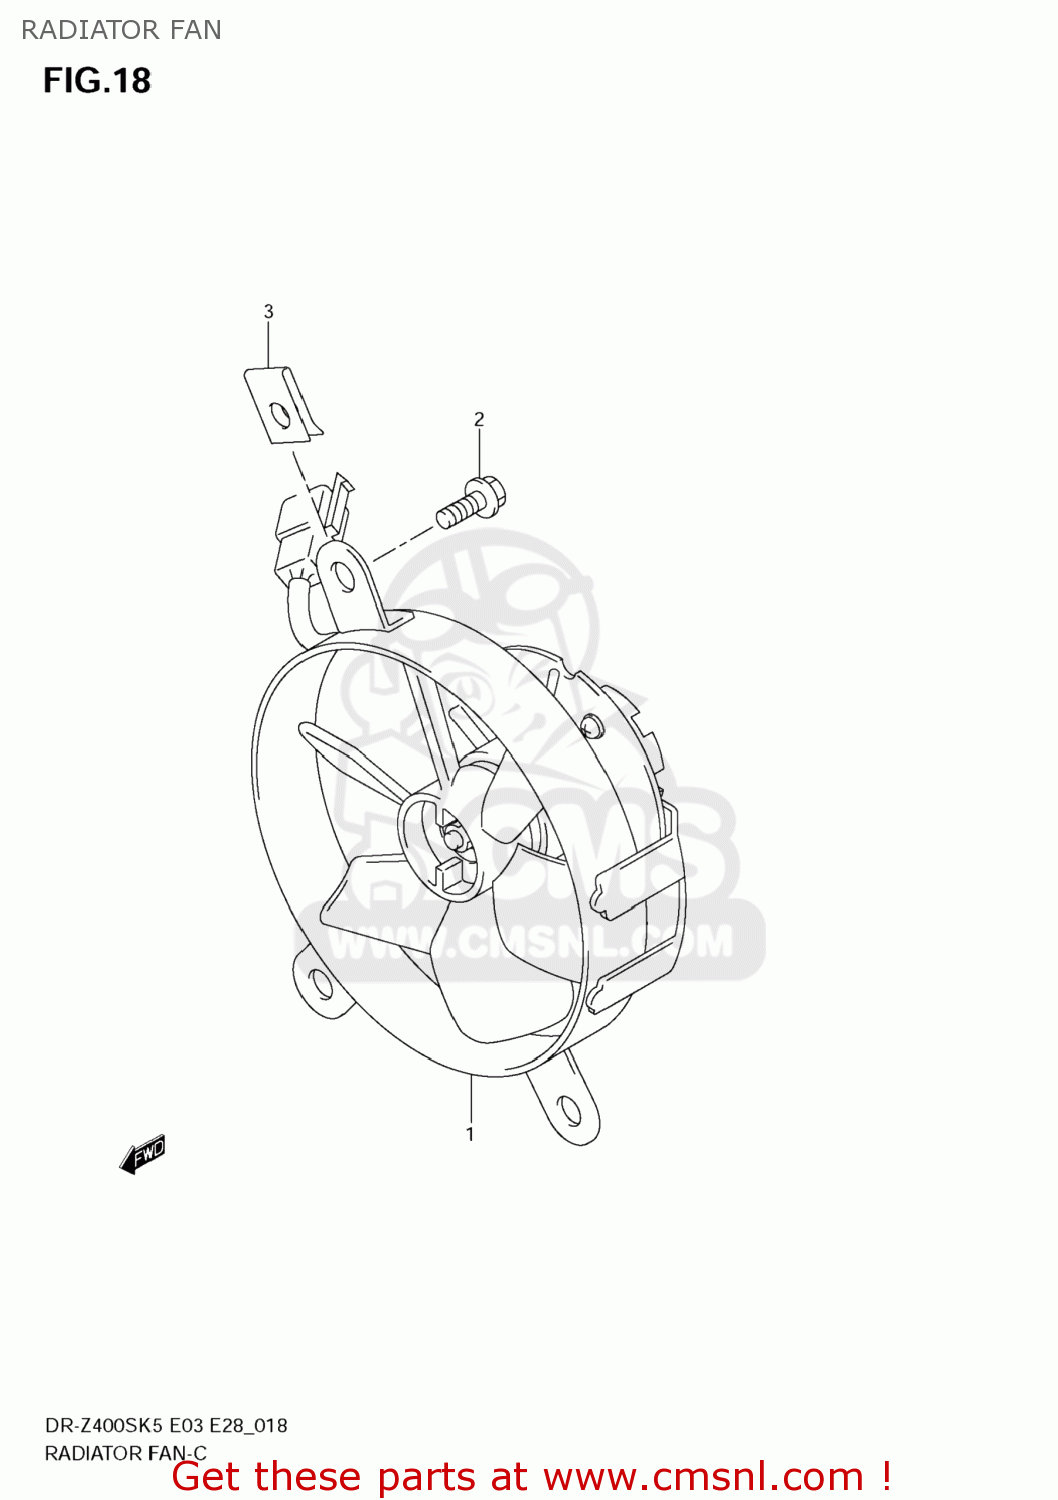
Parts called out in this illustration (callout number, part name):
1	FAN ASSY,RADIATOR
2	BOLT
3	NUT
